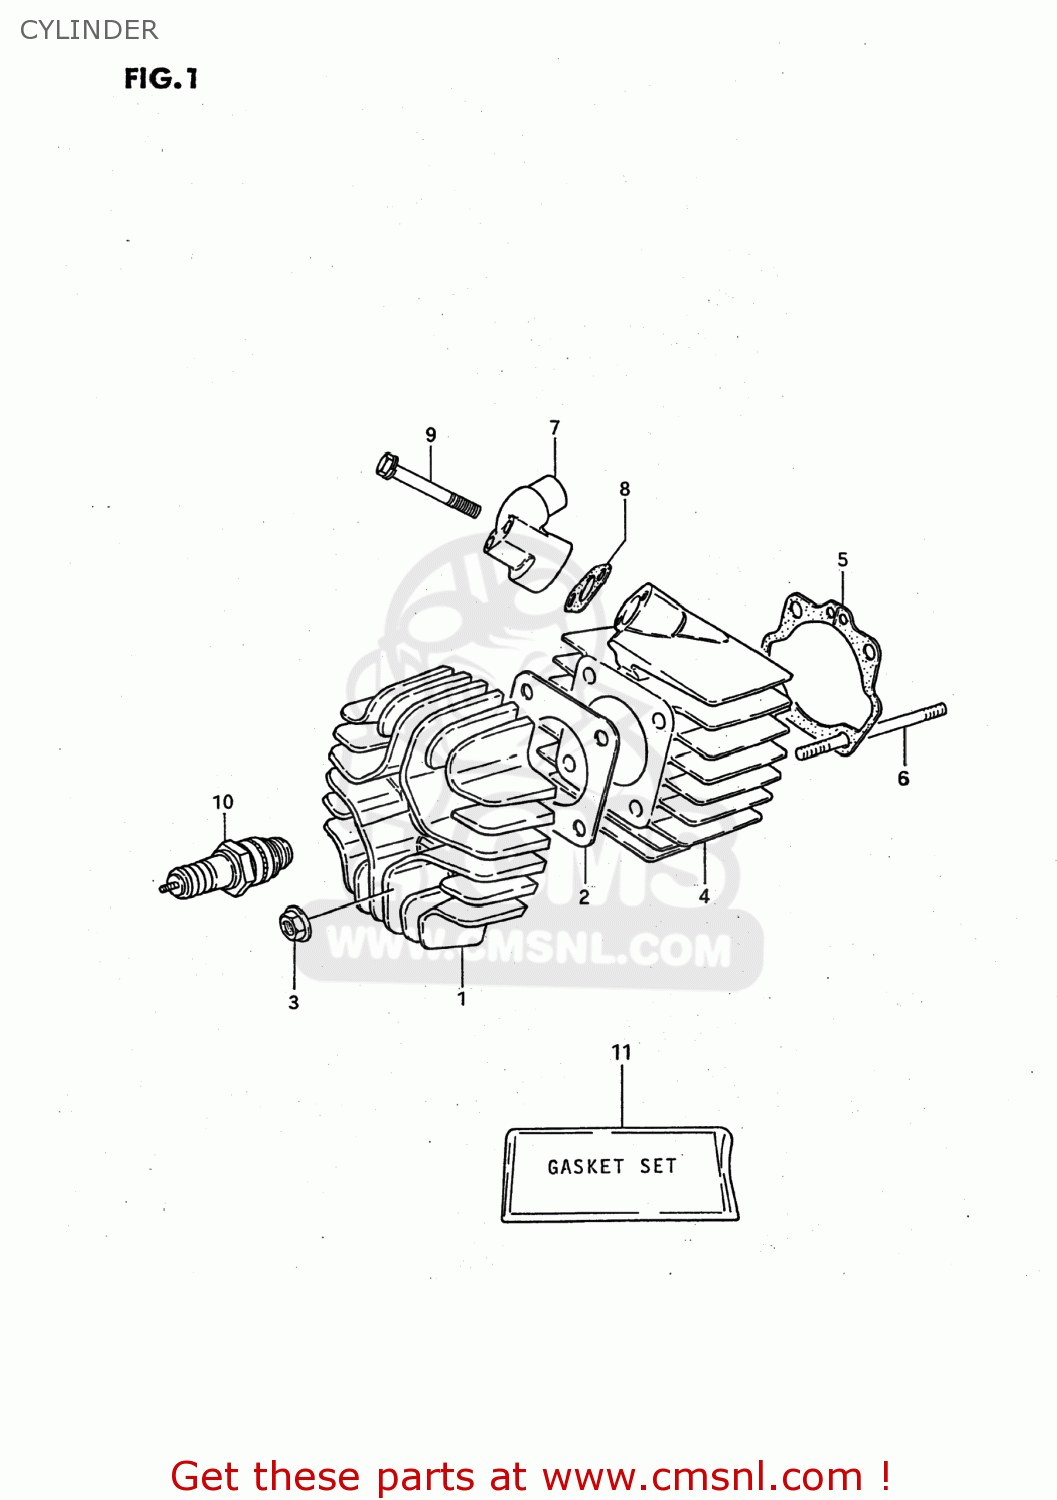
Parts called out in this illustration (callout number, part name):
1	HEAD,CYLINDER
2	GASKET,CYLINDER HEAD (NAS)
3	NUT
4	CYLINDER
5	GASKET,CYLINDER (NAS)
6	BOLT,STUD
7	PIPE,INTAKE
8	GASKET (NAS)
9	BOLT
10	PLUG,SPARK(BP4H)
11	GASKET SET (NAS)
